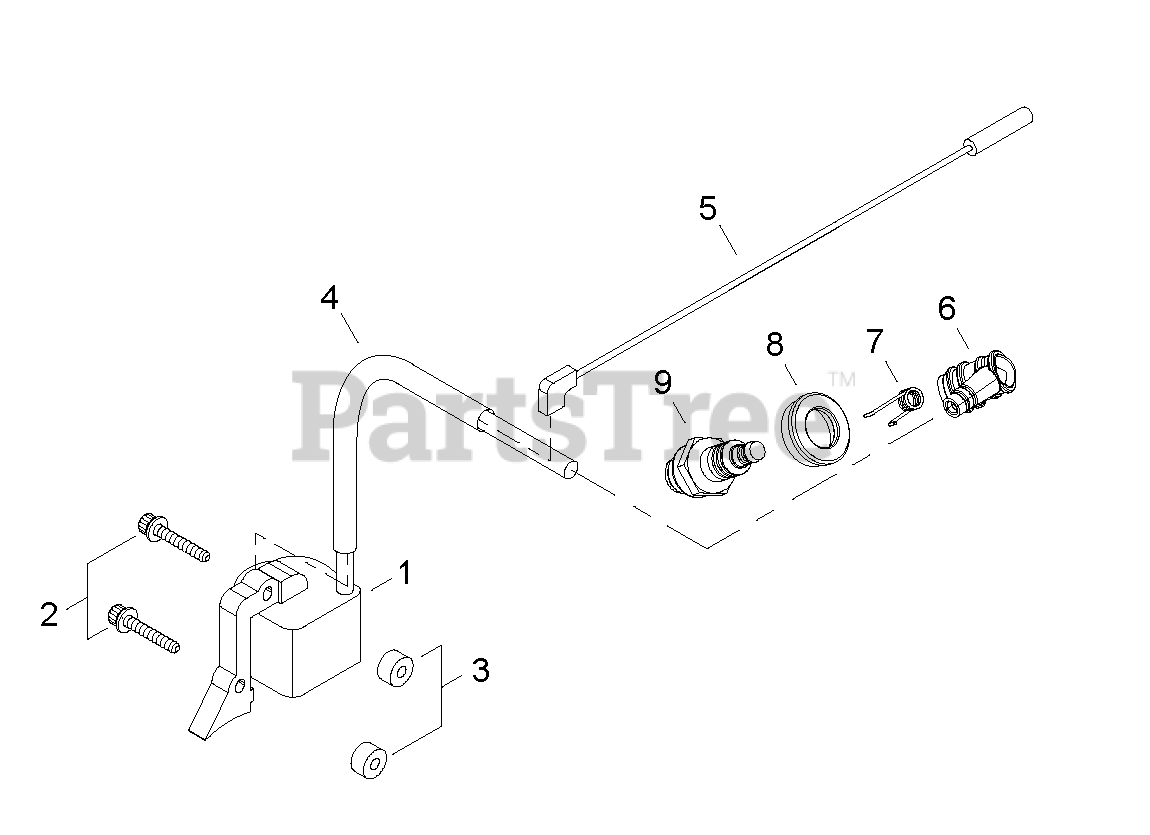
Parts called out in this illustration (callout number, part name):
1	COIL, IGNITION
2	BOLT, ADHESIVE M4×20
3	INSULATOR 4.2×11×6
4	TUBE, IGNITION COIL
5	LEAD - IGNITION L= 215
6	CAP, SPARK PLUG
7	TERMINAL, SPARK PLUG
8	SEAL, SPARK PLUG
9	SPARK PLUG - BPMR6A
